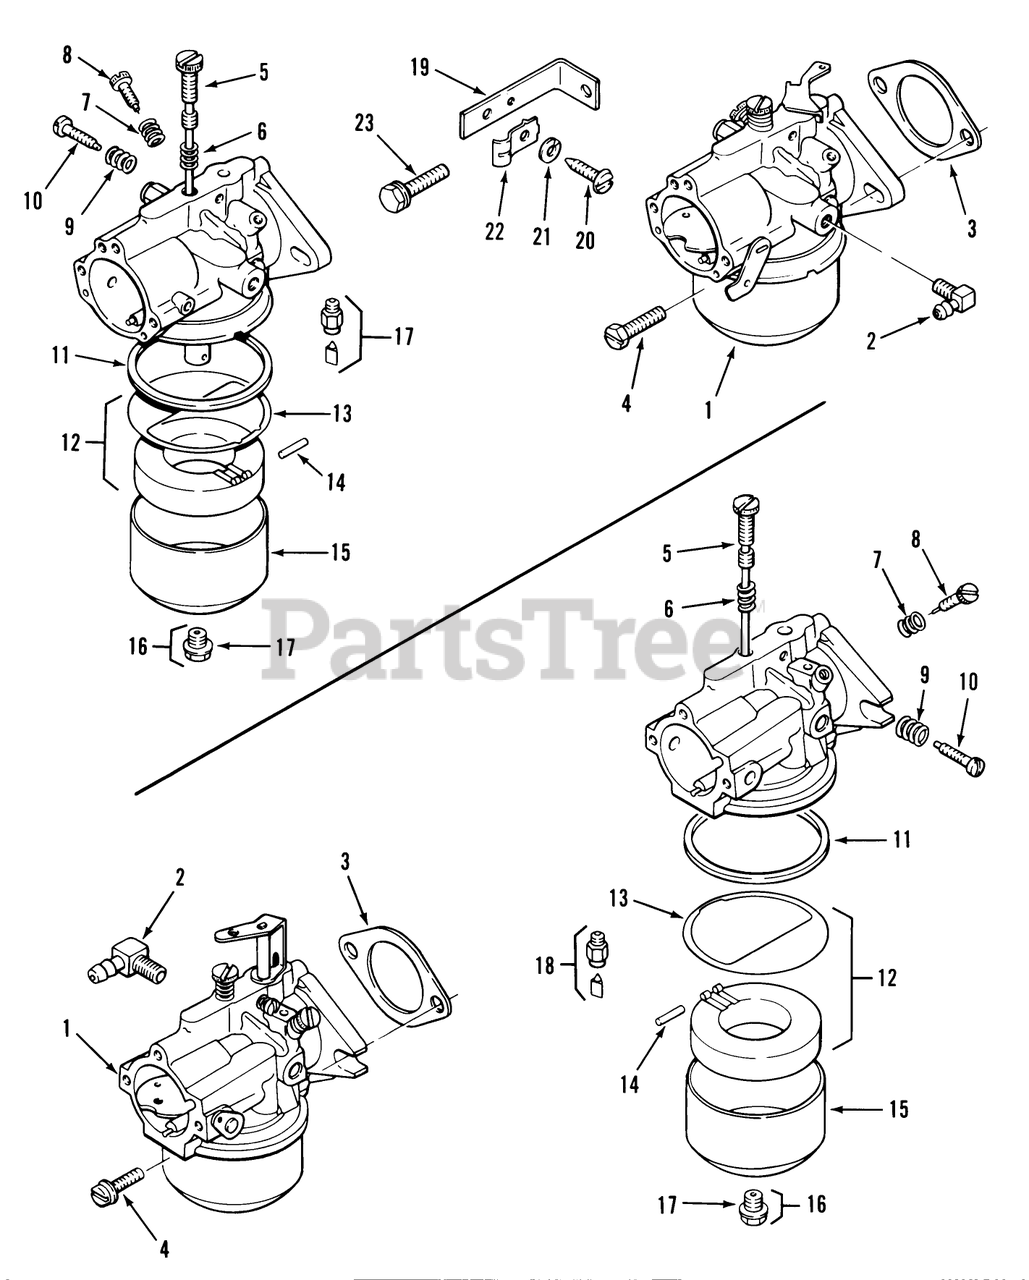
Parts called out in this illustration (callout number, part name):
1	KOHLER 41-053-18
2	KOHLER 25-155-02
3	KOHLER 210223
4	KOHLER X-140-1
5	KOHLER 232635
6	KOHLER 200383
7	KOHLER 200380
8	KOHLER 200438
9	KOHLER 232555
10	KOHLER 232556
11	KOHLER 200375
12	KOHLER 25-757-03
13	KOHLER 25-041-02
14	KOHLER 200376
15	KOHLER 200418
16	KOHLER 41-100-01
17	KOHLER 200372
19	KOHLER 41-126-37
20	KOHLER X-50-9
21	KOHLER X-19-1
22	KOHLER 235778
23	KOHLER X-132-5
